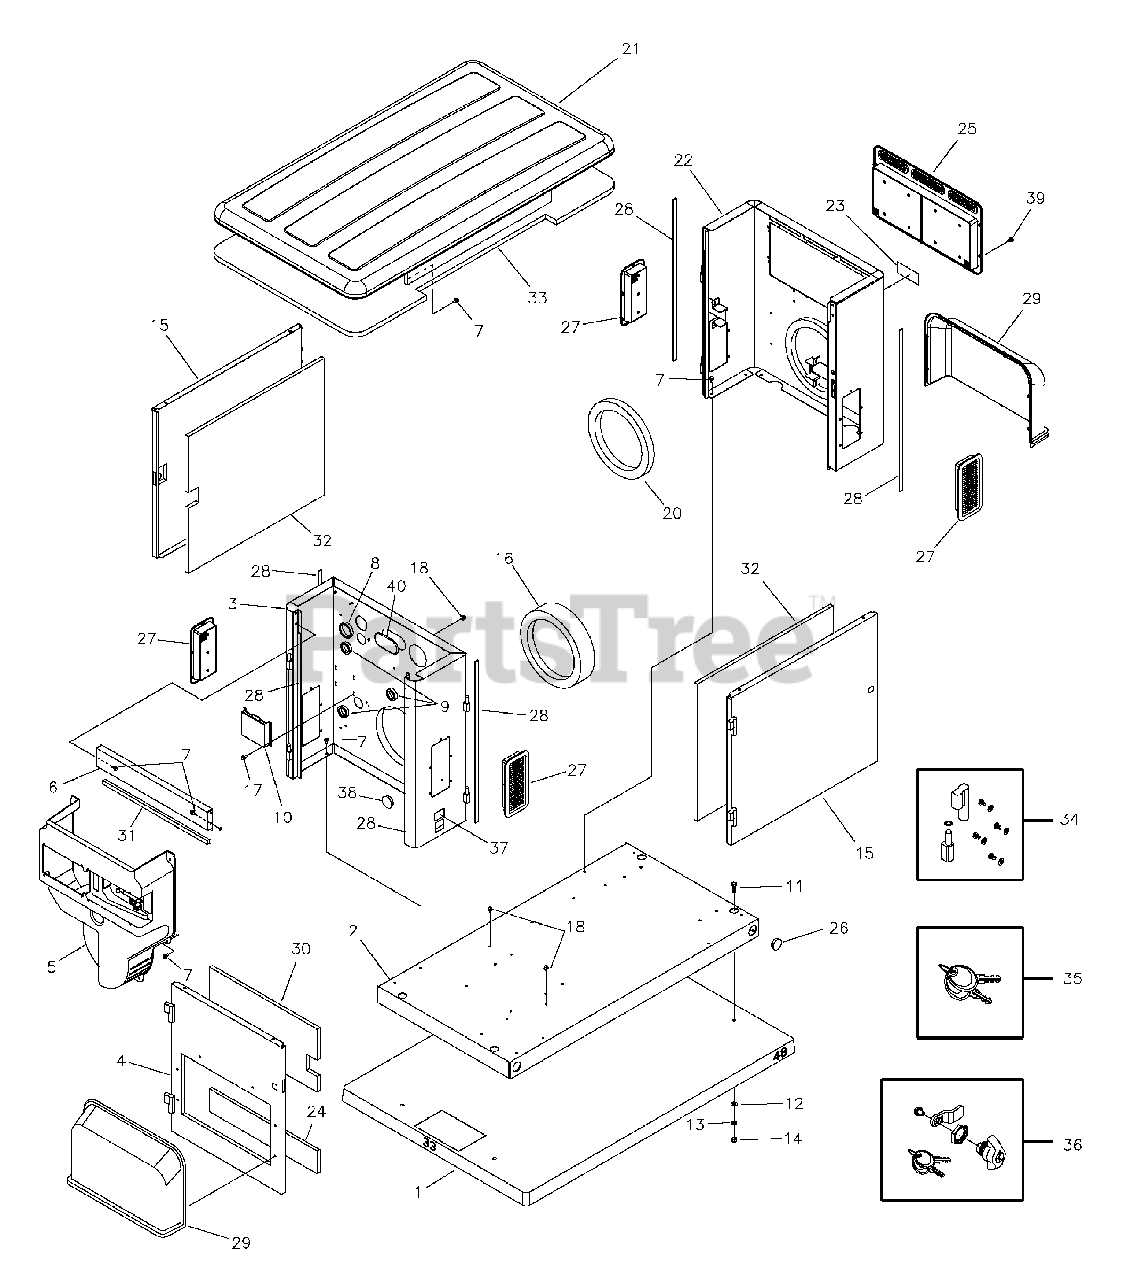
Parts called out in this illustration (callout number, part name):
3	BULKHEAD, Engine
7	BOLT
10	REGULATOR, Voltage
11	*CAPSCREW, Hex Head, 3/8-16 x 1
12	*WASHER, Flat, 3/8 - M10
13	*WASHER, Lock, 3/8
16	SEAL, Foam
20	SEAL, Foam
22	BULKHEAD, Alternator
29	COVER, Air Intake
37	DECAL
39	SCREW
